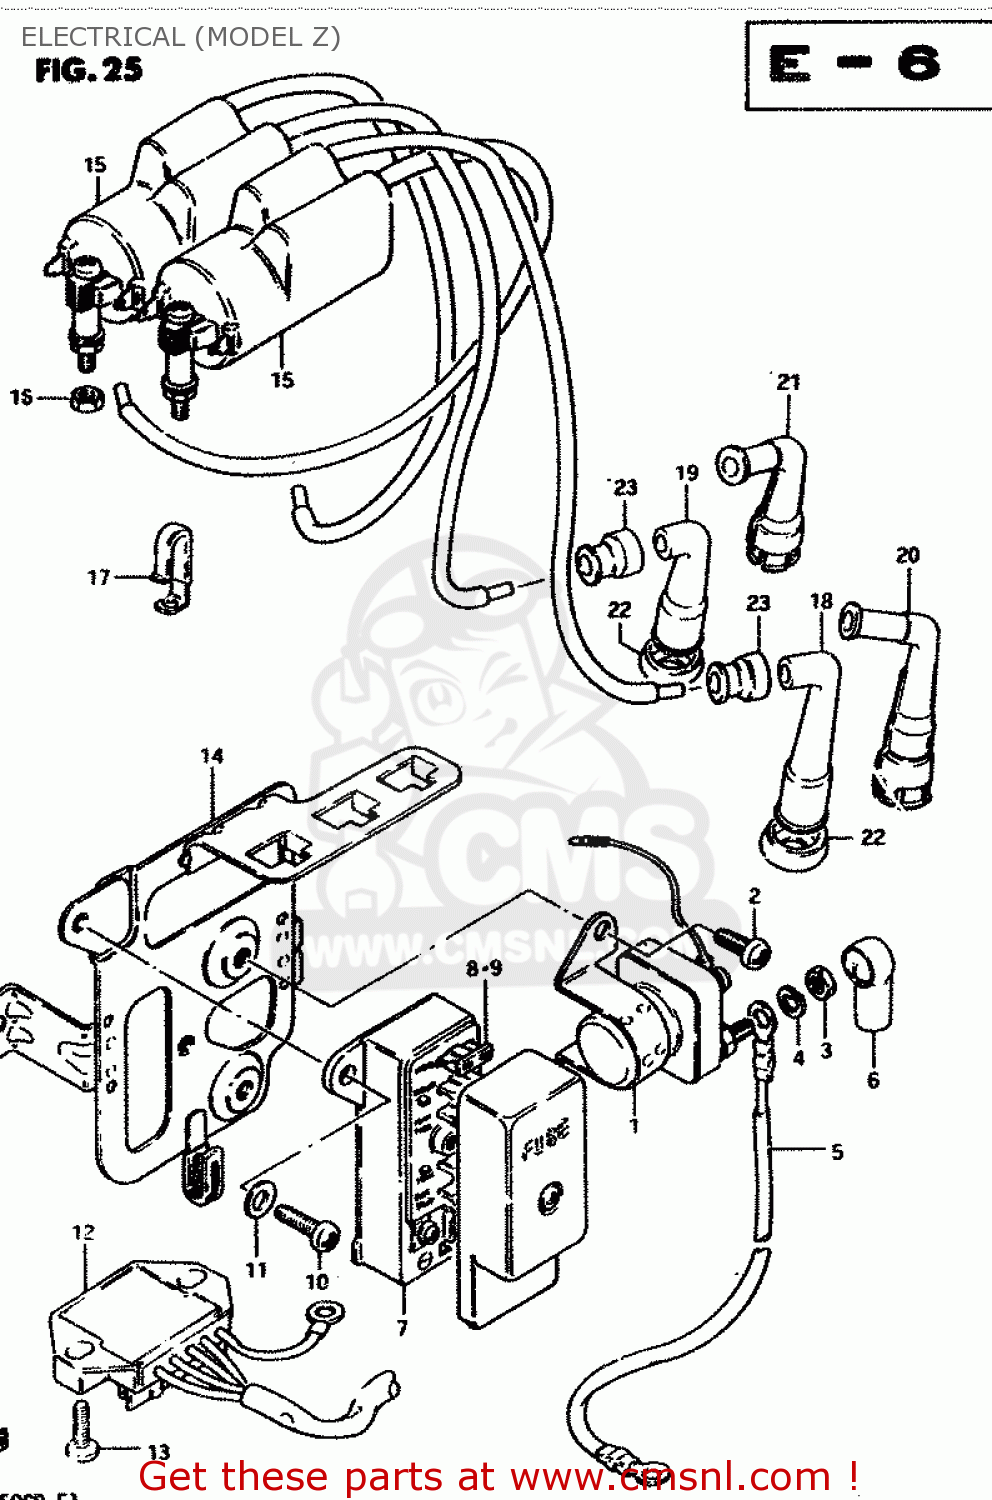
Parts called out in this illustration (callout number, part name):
1	RELAY ASSY,STARTING MOTOR
2	SCREW
3	NUT 6MM
4	LOCK WASHER
5	CABLE,STARTING MOTOR
6	CAP,STARTER RELAY
7	BOX ASSEMBLY,FUSE
8	FUSE(10A)
9	FUSE(15A)
10	SCREW 6X12
11	WASHER
12	RECTIFIER ASSEMBLY
13	SCREW 6X12
14	HOLDER COMP,ELECTRONIC PARTS
15	COIL ASSEMBLY,IGNITION
16	NUT
17	CLAMP
18	CAP ASSY,SPARK PLUG
19	CAP,SPARK PLUG
20	CAP,SPARK PLUG
21	CAP, SPARK PLUG (S)
22	SEAL,SPARK PLUG
23	SEAL,SPARK PLU
